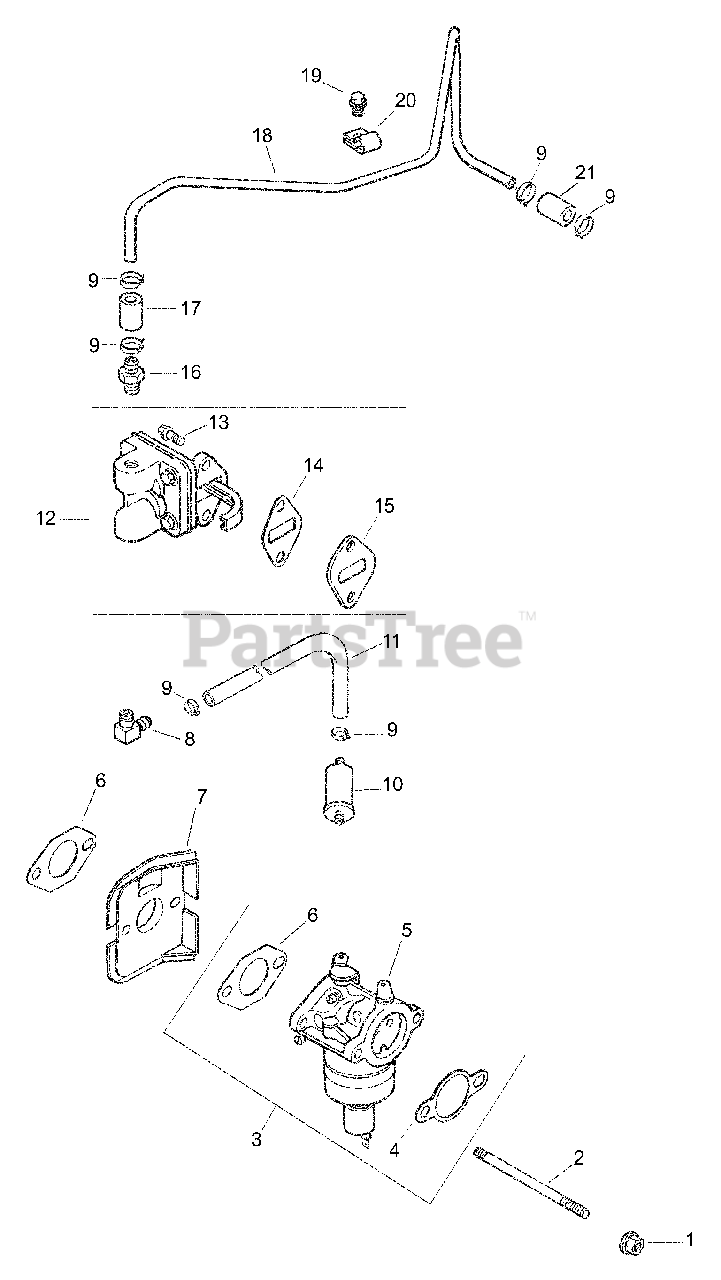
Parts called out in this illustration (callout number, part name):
1	Nut, Hex. Flange M6 x 1.0
2	Stud M6 x 1.0 x 116 (2)
3	Kit, Carburetor W/ Gaskets
4	Gasket, Air Cleaner
5	Carburetor Assembly
6	Gasket, Carburetor
7	Deflector, Heat
8	Connector, 90x Hose
9	Clamp, Fuel Line
11	Line, Fuel 3"
12	Kit, Fuel Pump
13	Screw, Hex. Flange M6 x 1.0 x 20
14	Gasket, Fuel Pump
15	Spacer, Fuel Pump
16	Connector, Straight Hose
17	Line, Fuel 1-1/4"
18	Line, Fuel - Metal
19	Screw, Hex. Flange M5 x 0.8 x 10
20	Clamp, Fuel Line
21	Line Fuel 2-1/2"
